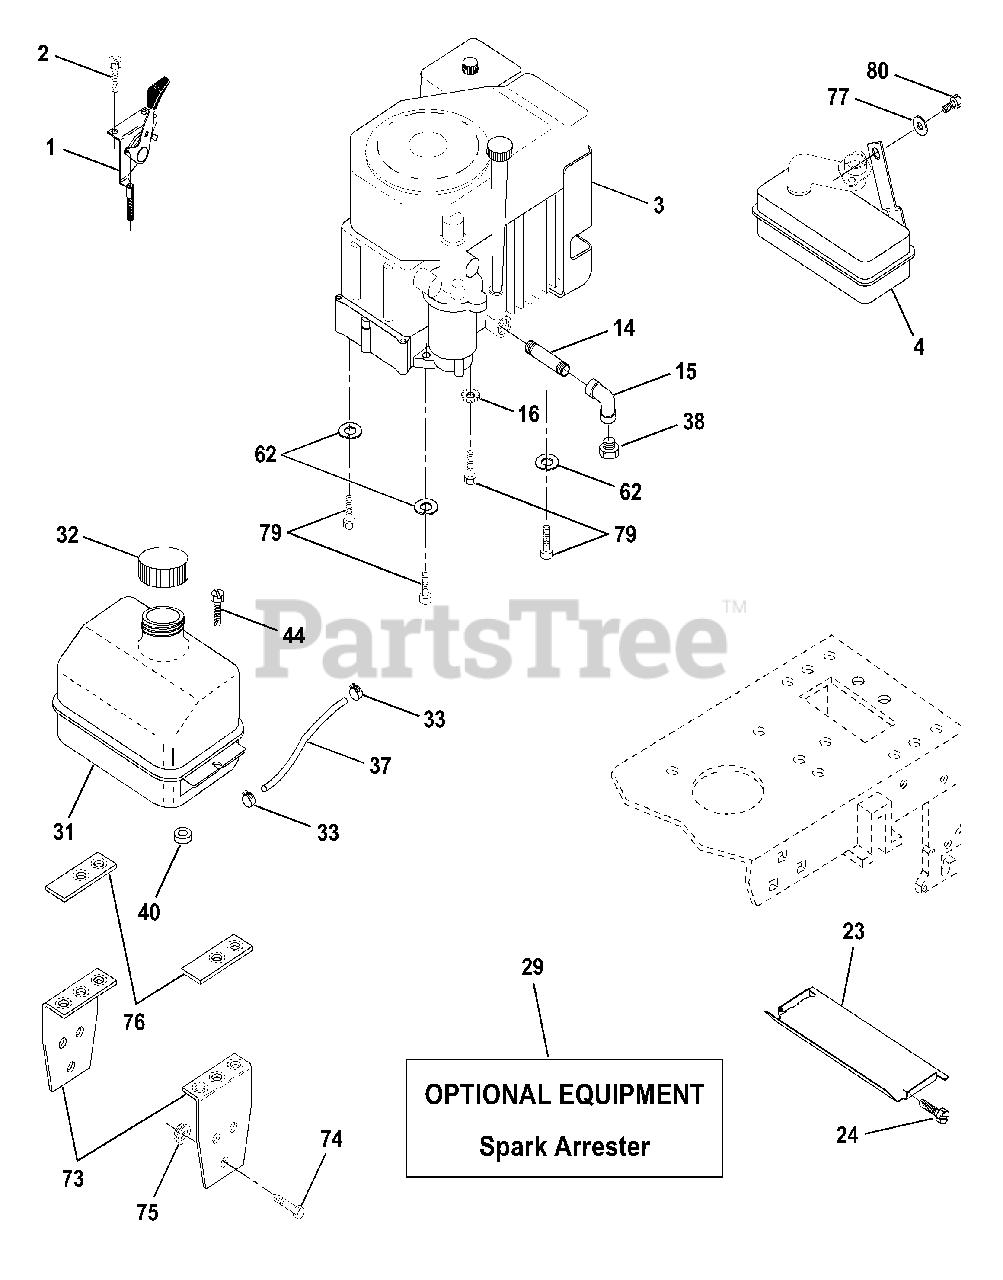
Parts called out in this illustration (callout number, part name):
1	Control Th/ch
2	Screw Hex Thd Cut 1/4-20x5/8 T
4	Muffler LT Kohler
14	Nipple Pipe 3/8 Npt X 3-1/2"
15	Elbow Std 90° 3/8-18 Npt
21	Bushing Snap Split
23	Shield Heat Browning
24	Screw Hex Thd Cut #10-24unc X 1/2
29	Kit Spark Arrestor
31	Fuel Tank Front 1 25
32	Cap Asm Fuel W/sym Vented
33	Hose Clamp
37	Fuel LIne
38	Plug Oil Drain (Order from Engine Mfg.)
40	Bushing Snap Split
44	Screw Hexwash Thdrol 3/8-16x3/4 Ty-tt
45	Bolt, Hex (Order from Engine Mfg.)
62	Washer Lock Hvy Hlcl Spr 5/16
63	Washer Lock Ext Tooth 5/16
73	Bracket Support Tank Fuel
74	Bolt, Hex 3/8-16unc X 1
75	Nut Lock Hex w/ins 3/8-16 UNC
76	Strap Support Fuel Tank
77	Washer, Flat
79	Bolt Hex
80	Bolt, Fin Hex 5/16-18 X 5/8
